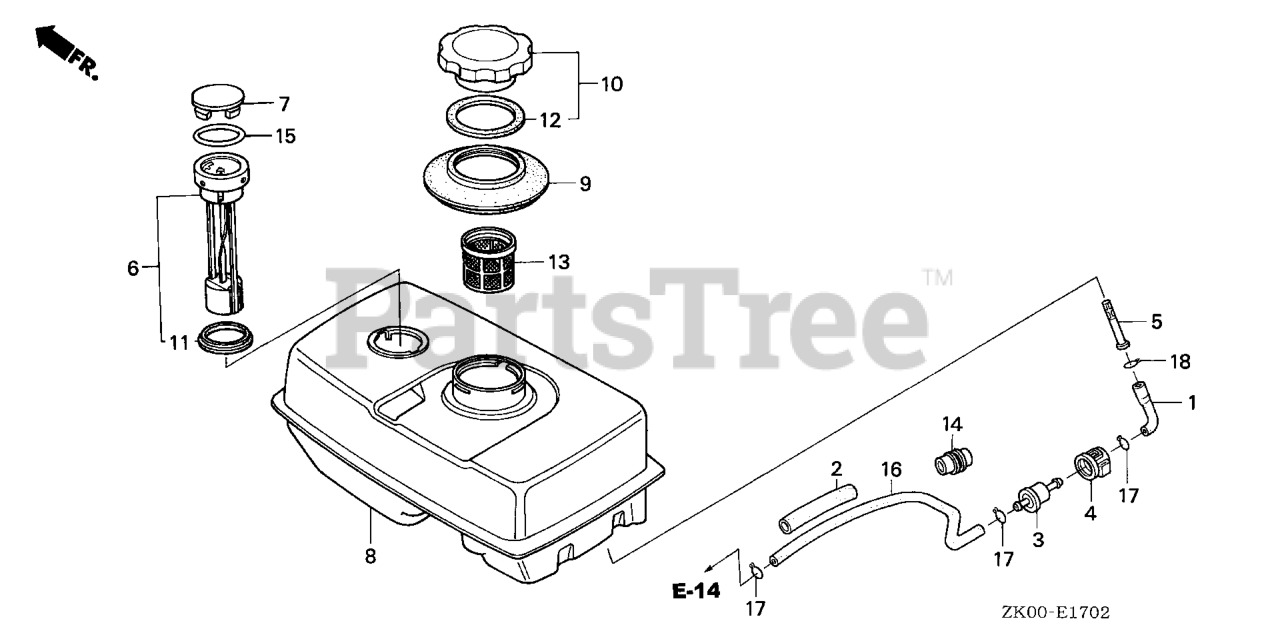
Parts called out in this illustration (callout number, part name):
1	BULK HOSE, FUEL (4.5X3000) (Honda Code 5137104). (4.5X140)
2	RUBBER, SUPPORTER (50MM)
3	FILTER, FUEL
14	RUBBER, FUEL (9X15X20)
16	BULK HOSE, FUEL (4.5X3000) (Honda Code 5137104). (4.5X140)
17	CLIP, TUBE (B8)
18	CLIP, TUBE (B8)
